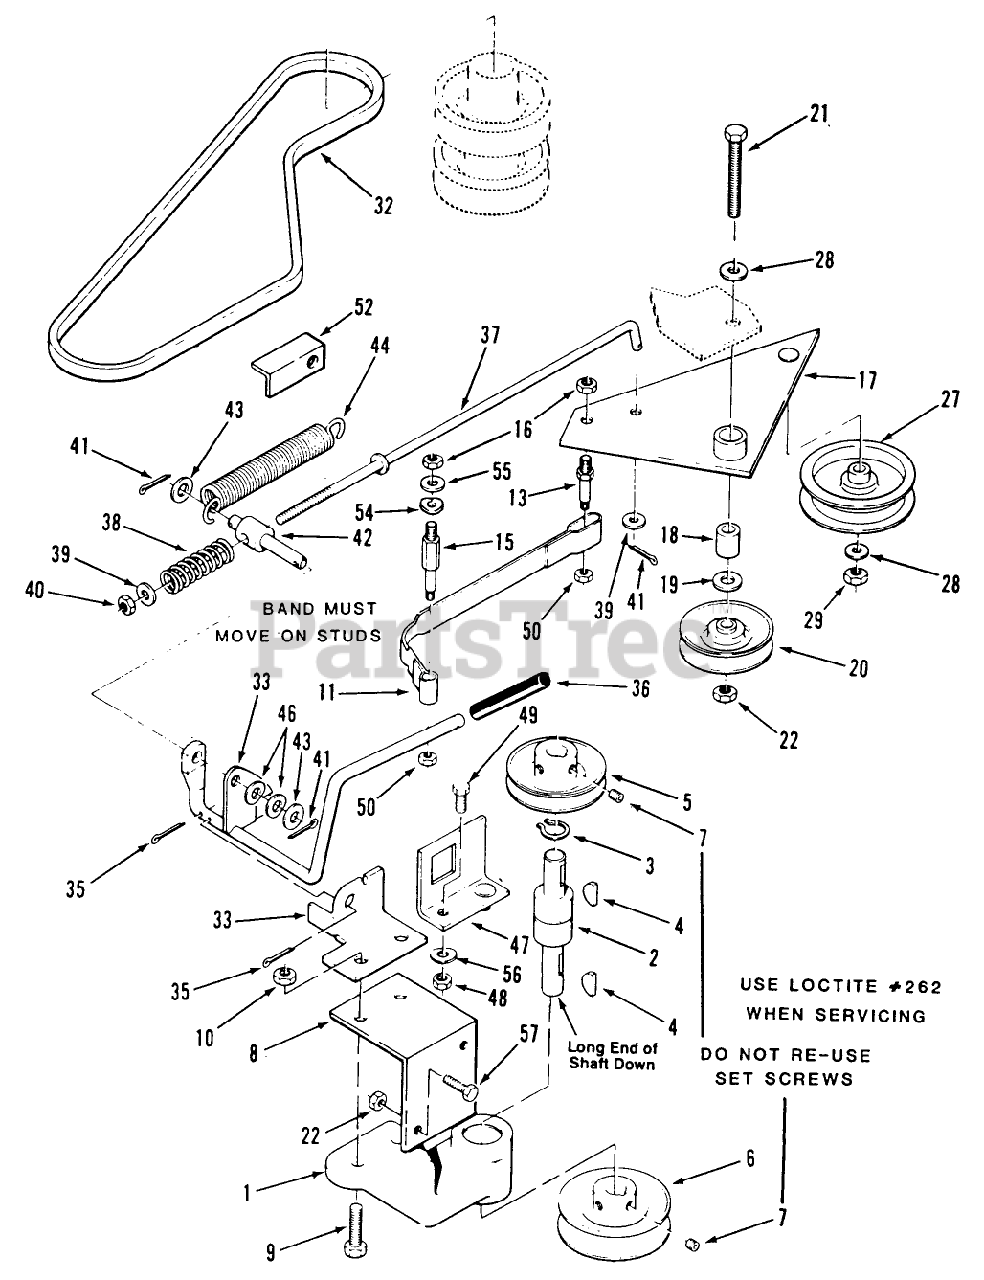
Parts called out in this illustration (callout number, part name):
1	Jack Shaft Housing
2	BEARING-INT SHAFT
3	Snap Ring
4	KEY-WOODRUFF
5	PULLEY CAST IRON
6	PULLEY
7	Set Screw
8	JACKSHAFT-BRACKET R
9	Bolt
10	NUT
11	BAND BRAKE
13	STUD-SHOULDER
15	STUD-SHOULDER LONG
16	Nut
17	BLADE LEVER ASSY R
18	SPACER
19	Washer
20	IDLER PULLEY
21	Bolt
22	NUT
27	Idler Pulley
28	Washer
29	NUT-HEX, JAM
32	BELT-V
33	ASSY HANDLE PTO CLUT
35	Cotter Pin
36	GRIP
37	ASSY ROD PTO
38	SPRING COMPRESSION
39	WASHER 5/16 SAE
40	Nut
41	Cotter Pin
42	TRUNNION
43	Washer
44	SPRING R
46	WASHER-SPRING
47	ASS'Y-BRACKET (L. R
48	Nut
49	H H C S
50	Nut
52	PTO INDICATOR BRC R
54	WASHER
55	WASHER 5/16 SAE
57	Bolt
